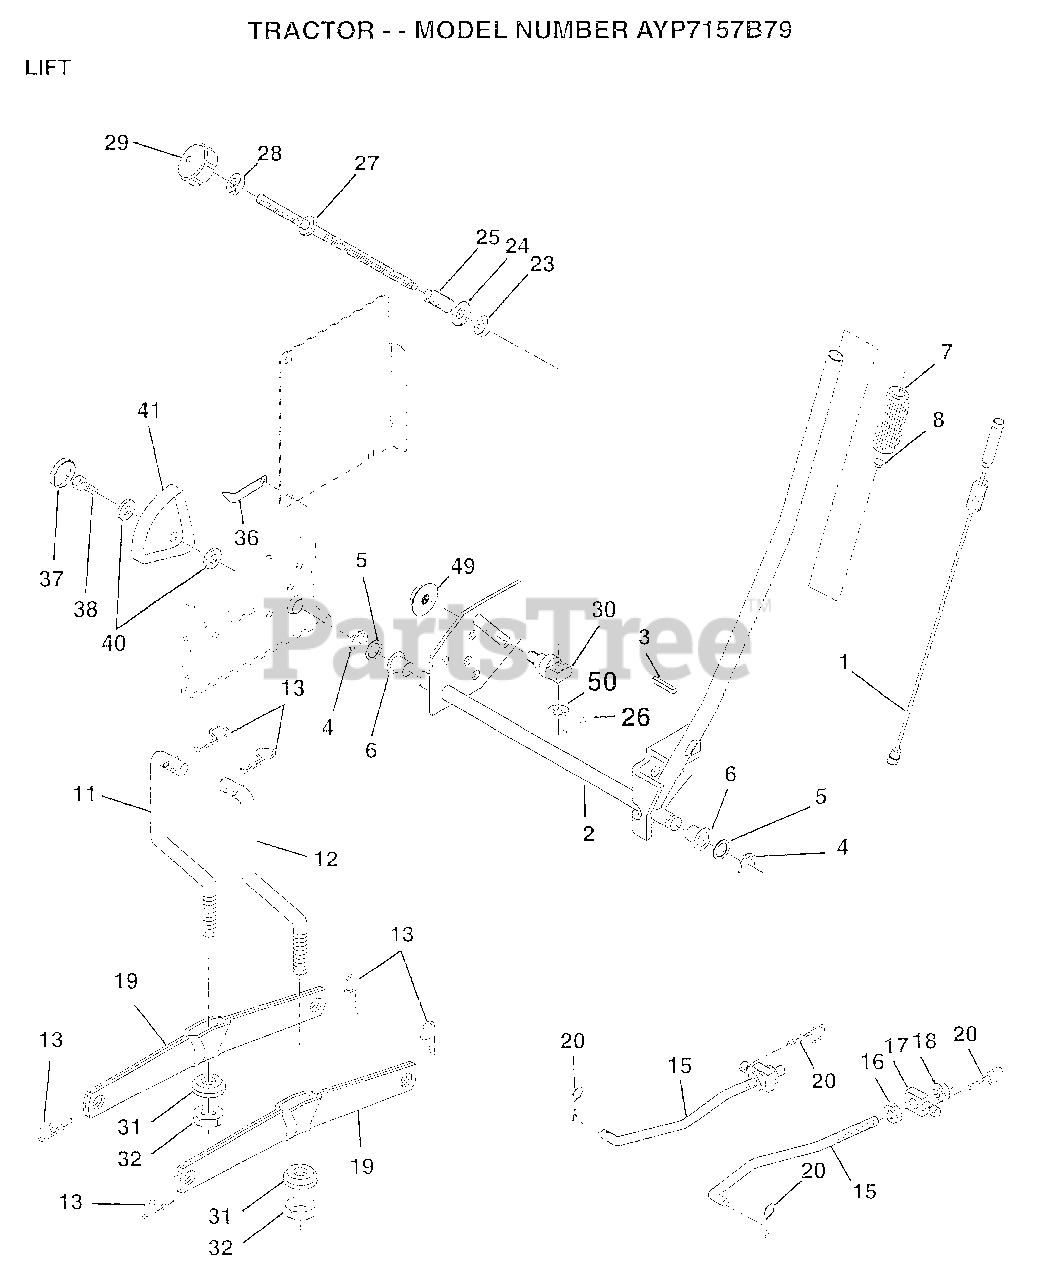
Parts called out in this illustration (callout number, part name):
1	WIRE ASM W.SPRING
2	"SHAFT ASM LIFT,RH"
3	PIN-GROOVE LT
5	WASHER
6	NYLON BEARING
7	GRIP HANDLE
15	LINK.FRONT
16	NUT
17	TRUNION
18	NUT.LK.W/WSH.1/2.
19	ARM SUSP REAR
20	RETAINER.SPRING
23	NUT T
24	WASHER
25	SPRING T
28	NUT
29	KNOB INF 3/8-16
30	TRUNNION
31	BEARING PVT LH
32	NUT.CROWNLOCK.3/8
36	POINTER-INDICAT
37	"PLUG,HOLE"
38	SCREW
40	WASHER
41	HEIGHT INDICATOR
49	NUT.HXFLG.LOCK.
